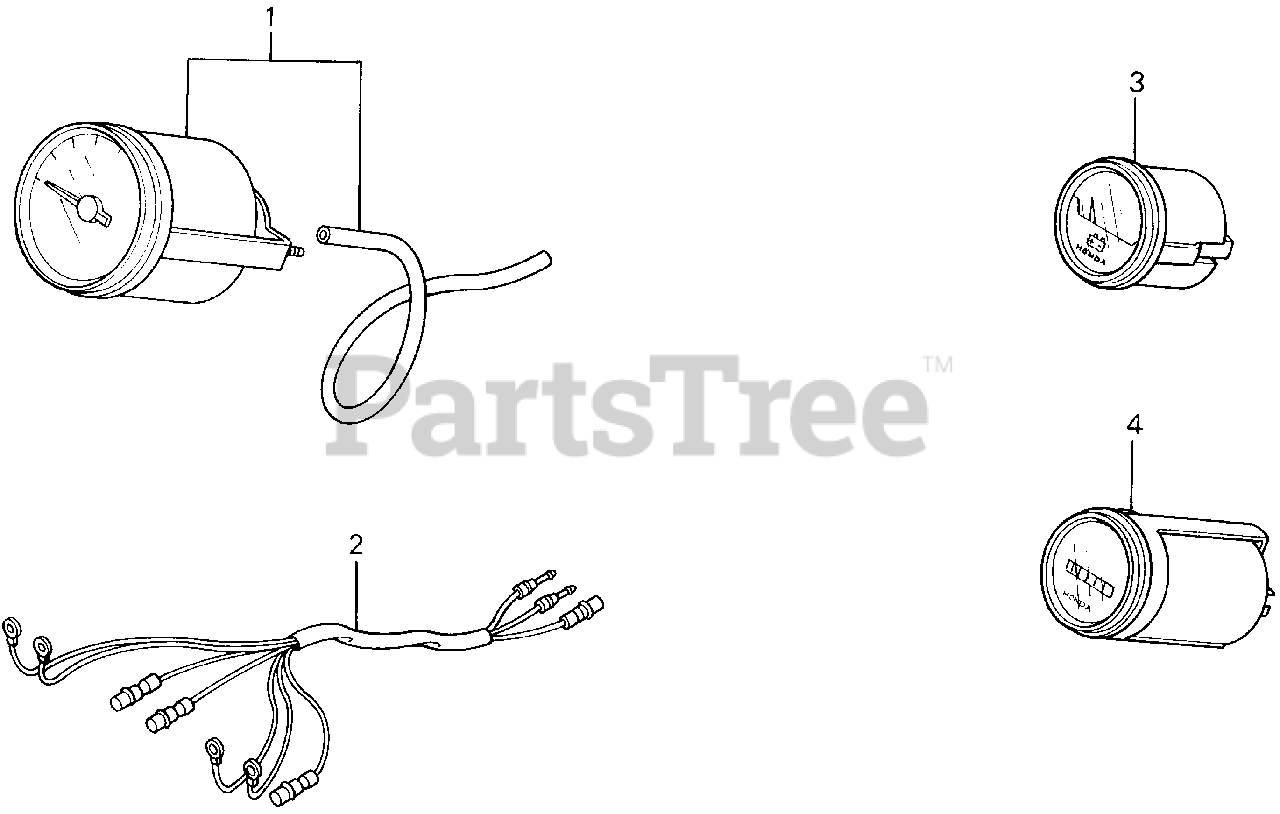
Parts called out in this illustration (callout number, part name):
1	SPEEDOMETER KIT
2	HARNESS ASSY., METER (B)
3	METER ASSY., VOLT (NOT AVAILABLE)
4	METER ASSY., HOUR L.C.D.
